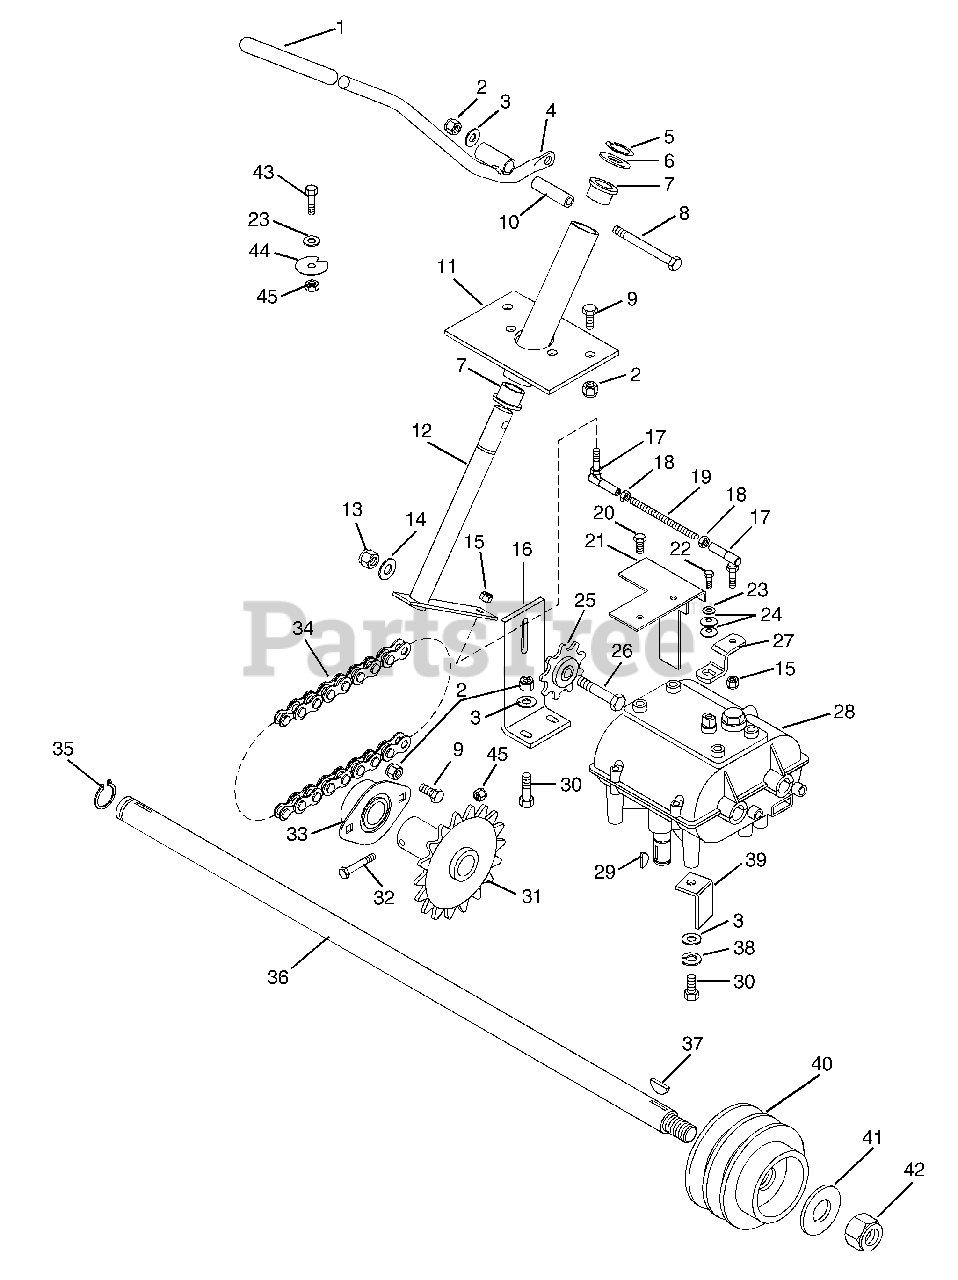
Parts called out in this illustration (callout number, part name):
1	Grip, PTO Lever
2	Nut-Locking-Nylon .312-18
3	Washer-Flat-Steel .344 x .688 x .065
4	Weldment, Shift Lever
5	Ring-Retaining-External .689 x .077
6	Bearing-Needle-Thrust .752 x 1.24 x .031
7	Bushing-Flange .762 x 1.0 x .580 x 1.48
8	Bolt-Hex .31-18 x 2.75
9	Bolt-Hex .31-18 x .75 Grade 5
10	Bushing, Steel .328 x .497 x 1.53
11	Weldment, Shifter Tube
12	Weldment, Shifter Shaft
13	Nut-Locking-Nylon .375-16
14	Washer-Flat-Steel .406 x .812 x .065
15	Nut-Locking-Center .250-28
16	Bracket, Idler Sprocket
17	Ball, Joint Disconnecting
18	Nut .250-28
19	Rod, Transmission Shifting
20	Bolt-Tapping .312-18 x .62
21	Guard, Chain
22	Bolt-Hex .25-28 x .75 Grade 8
23	Washer-Flat-Steel .281 x .62 x .065
24	Washer, Belleville
25	Sprocket, Idler
26	Bolt-Hex .38-16 x 1.75 Grade 5
27	Arm, Transmission Shift
28	Transmission, Pro Line
29	Key, Woodruff .19 x .75
30	Bolt-Hex .31-18 x 1.00 Grade 5
31	Weldment, 28T 1/2 P Sprocket
32	Bolt-Hex .25-20 x 2.25 Grade 8
33	Bearing-Flange 1.000 x 2.125 x 3.75
34	Chain, No. 40
35	Ring-Retaining-External .984 x .042
36	Shaft, Jack
37	Key, Woodruff .25 x 1
38	Washer-Lock .313 x .078
39	Guard, V-Belt
40	Pulley, Jack Shaft
41	Washer-Flat-Steel .812 x 1.50 x .139
42	Nut-Locking-Jam-Nylon .75-10
43	Bolt-Hex .25-20 x .63
44	Washer, Flat Notched
45	Nut-Locking-Nylon .250-20
